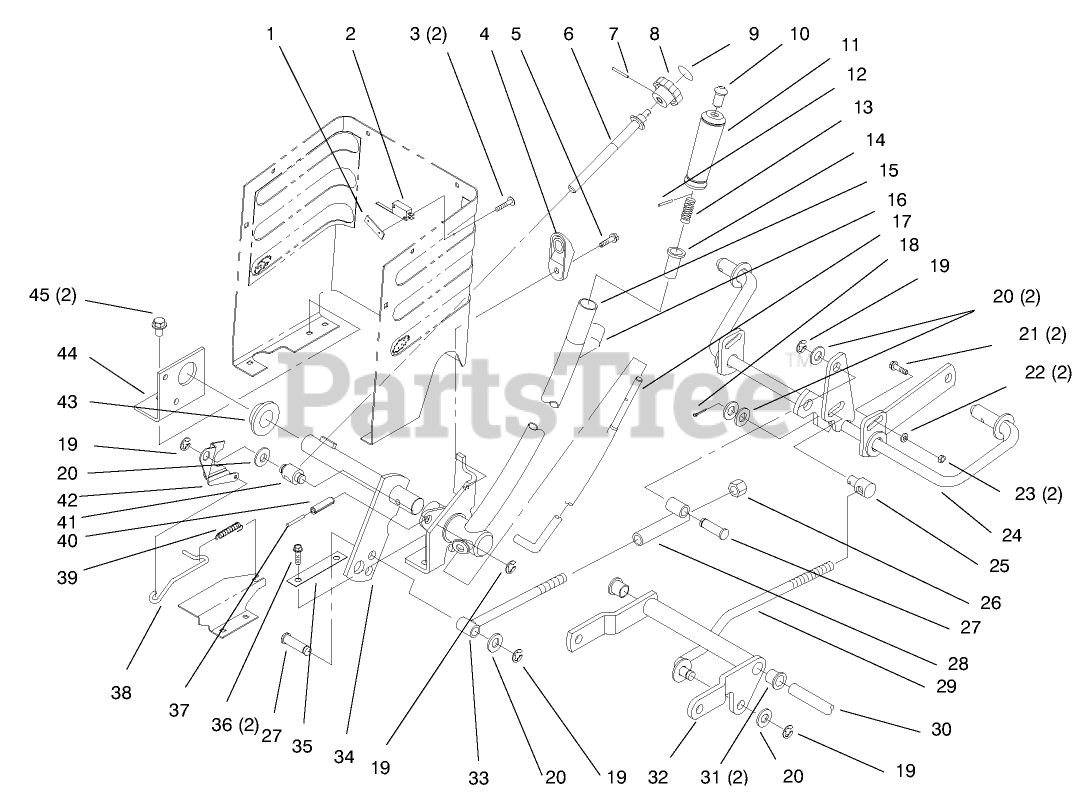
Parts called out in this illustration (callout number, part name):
1	NUT-SPEED
2	SWITCH-MICRO
3	SCREW-PPHTF
4	WEDGE - HOC
5	SCREW-HWH
7	PIN-SPIROL
10	TIP-ROD
11	GRIP-HANDLE
12	PIN-SPIROL
13	SPRING-COMPRESSION
14	RETAINER-SPRING
15	LEVER-LIFT
16	DECAL-LIFT
17	ROD-LEVER, LIFT
18	PIN-COTTER
19	RING-RETAINING, EXTERNAL
20	WASHER-FLAT
21	BOLT-CARR
22	WASHER-FLAT
23	NUT-LOCK, NI
24	SHAFT-GAGE
26	NUT-LOCK, NI
31	BUSHING-FLANGE
32	ARM-PIVOT
34	SHAFT-LIFT
36	SCREW-HWHTF
37	PIN-SPRING
38	ROD - HOC INDICATOR
39	SPRING - EXTENSION
40	PIN-ROLL
42	PLATE - HOC GAGE
43	BEARING-FLANGE
44	BRACKET-PIVOT, LINKAGE
45	SCREW-HWHTF
